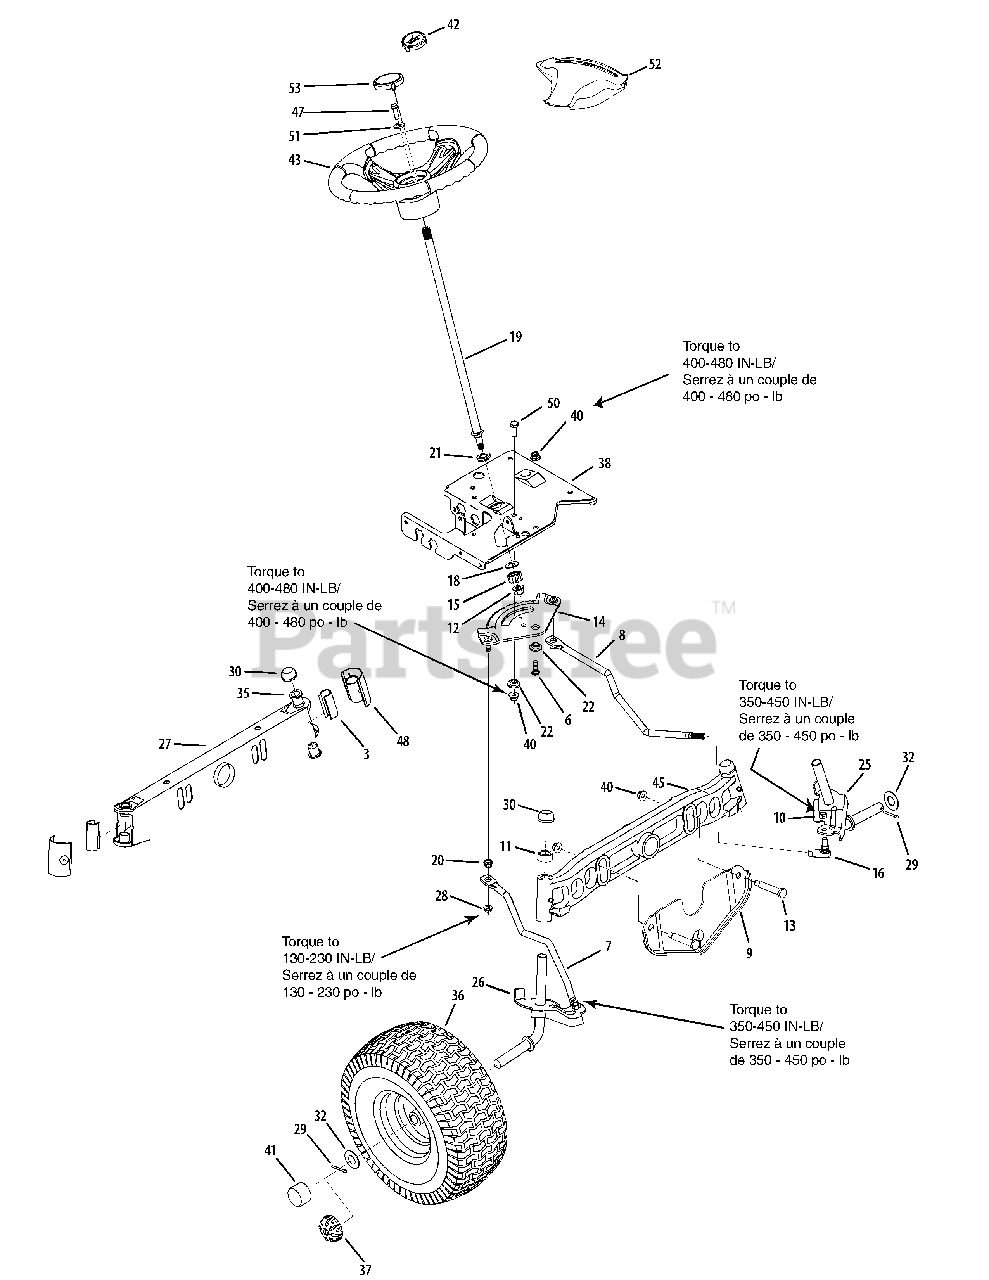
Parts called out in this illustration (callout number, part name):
3	Axle End Cap - Std.
6	Hex Cap Screw 3/8-16 x 1.00 Gr. 5 Spec.
7	RH Drag Link
9	Front Deck Hanger Brkt. (Style 6)
10	Hex Cent. L-Nut 3/8-24
11	Spacer .71 ID x .125 OD x .56" Lg.
12	Flange Lock Nut, 7/16-20
13	Shoulder Bolt .50 x 2.38: 3/8-16
14	Steering Gear, 11/90 Ratio
15	Steering Pinion Gear
16	Ball Joint, 7/16 - 20
18	Fl. Washer .510 x 1.120 x .060
19	Steering Shaft, .625 OD x 24.25
20	Plastic Bushing .380 ID
21	Hex Flange Bearing, 5/8
22	Shoulder Spacer
25	LH Axle Assembly, .750 Dia. (46", 50" & 54")
26	RH Axle Assembly, .750 Dia. (46", 50" & 54")
28	Hex Flange L-Nut 5/16-18 Gr. 5
29	Cotter Pin 5/32" Dia. x 1.25
30	Push Cap, .750
32	Flat Washer .781 ID x 1.90 OD
35	Flange Bearing .760 ID x .937 OD
36	Wheel Assembly
36	Rim Only
37	Hub Cap
38	Steering Support Bracket
39	Shld. Scr. .500 Dia. X .335" Lg.
40	Hex Flange L-Nut 3/8-16 Gr. F
42	Steering Wheel Cap - Small w/logo
43	Steering Wheel - 3 Spokes Soft Grip
45	Cast Iron Pivot Bar (.750 dia.)
47	Hex Screw 5/16-18 X 1.00 Spe cial
48	Pivot Bar End Cap
50	Hex Screw 3/16 x 1.00
51	Flat Washer .406 ID x .875 OD x .105
52	Steering Wheel Cover - MTD
53	Steering Wheel Cap - Small Toro
